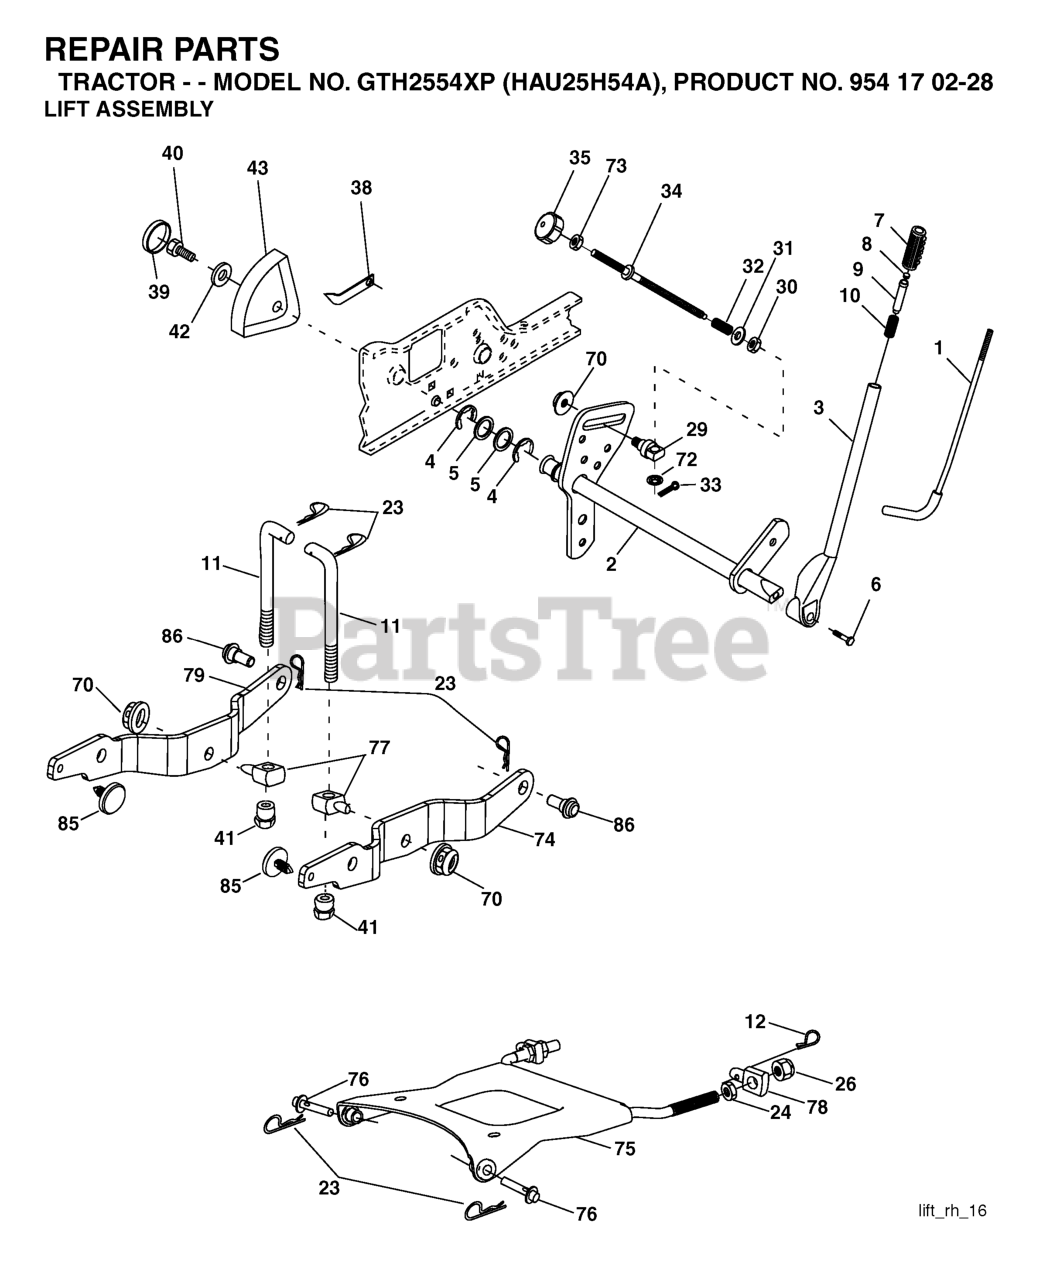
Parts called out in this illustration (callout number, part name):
1	LEVER ROD LT
2	SHAFT ASM., LIFT VGT
3	LEVER ASSY-LIFT RH
5	Washer 29/32 x 1 - 1/4 x 16 Ga.
6	Bolt, Fin Hex 3/8-16 x 1-1/12
7	GRIP HANDLE
8	PLUNGER BUT KIT
9	PLUNGER BUT KIT
10	SPRING 0.620D X 2.125
11	LIFT LINK
12	SPRING RETAINER
23	RETAINER-SPRNG RB
24	NUT.HEX.JAM.1/2-13
26	NUT.LK.W/WSH.1/2.
32	SPRING.COMP.INF.H
33	COTTER PIN
34	ROD.LIFT.ADJUSTABLE
35	KNOB INF 3/8-16
38	POINTER, HEIGHT INDICATOR(2 2)
40	SCREW 5/16-18X1
41	NUT, LIFT LINK 7/16-20
43	HEIGHT INDICATOR
70	NUT
72	NUT PUSH M
73	NUT
74	ARM.SUSP.REAR.RH
75	PLATE ASM SUSP FRONT
76	PIN.FLANGE
79	ARM SUSPENSION LH
85	INSERT WEAR (3 2)
86	BOLT.SHOULDER
